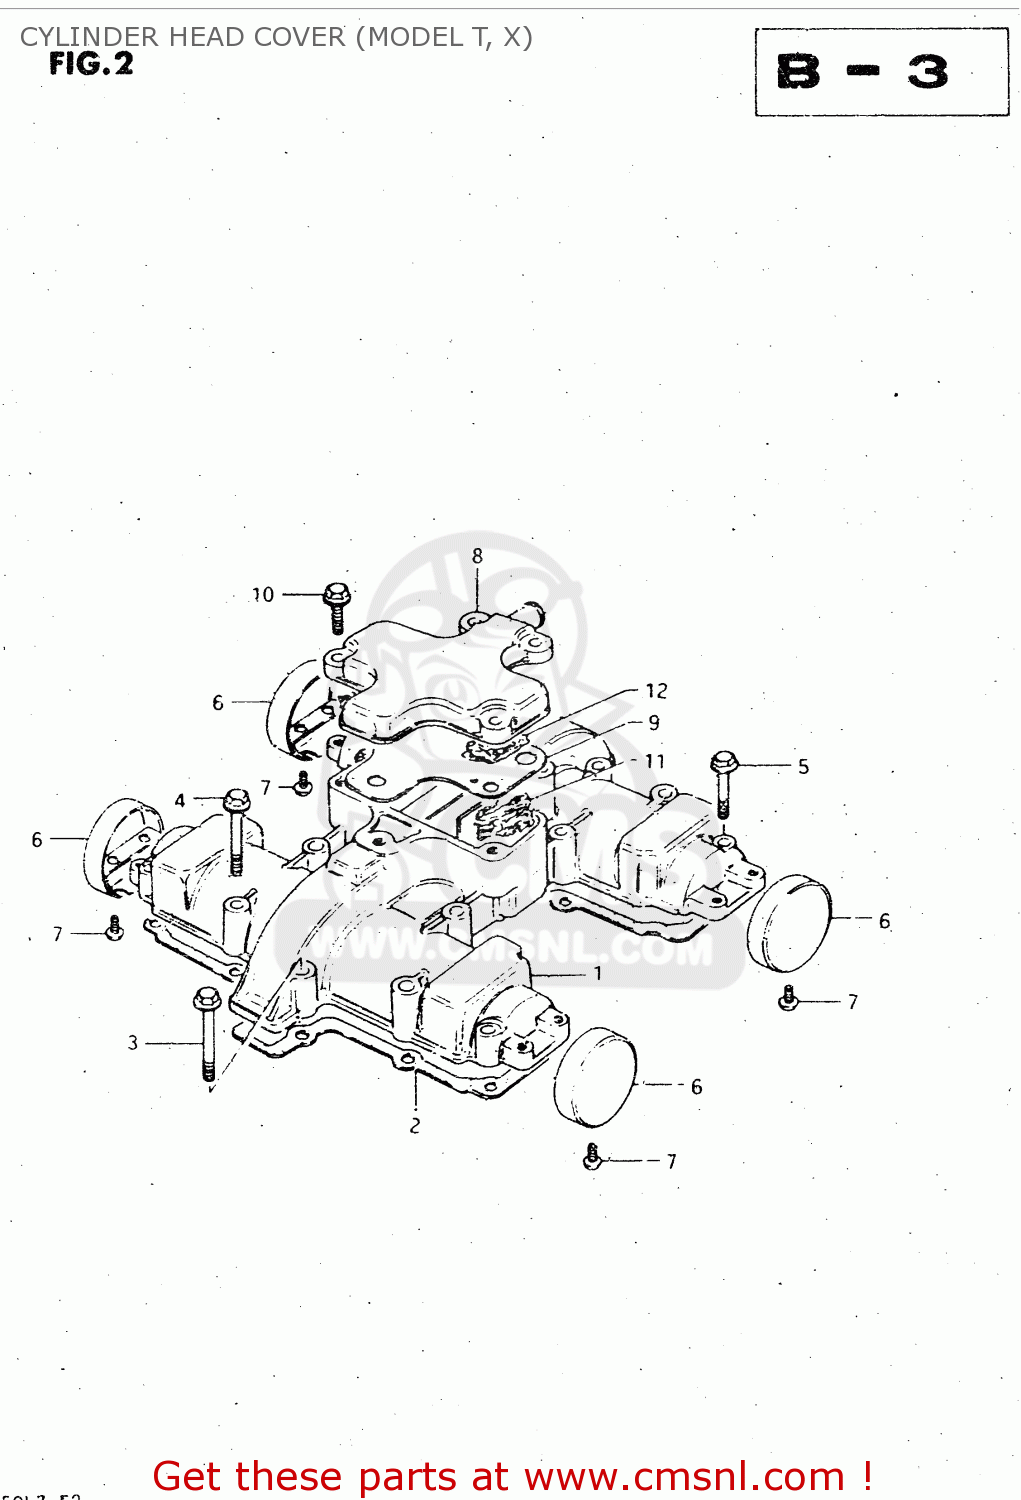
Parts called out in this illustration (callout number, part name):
1	COVER,CYLINDER HEAD
2	GASKET,CYLINDER HEAD COVER
3	BOLT
4	BOLT
5	CAP,CYLINDER HEAD COVER
6	SCREW
7	COVER,BREATHER
8	GASKET (MCA)
9	BOLT,REAR
10	COVER,BREATHER
11	SEPARATOR,OIL BREATHER
